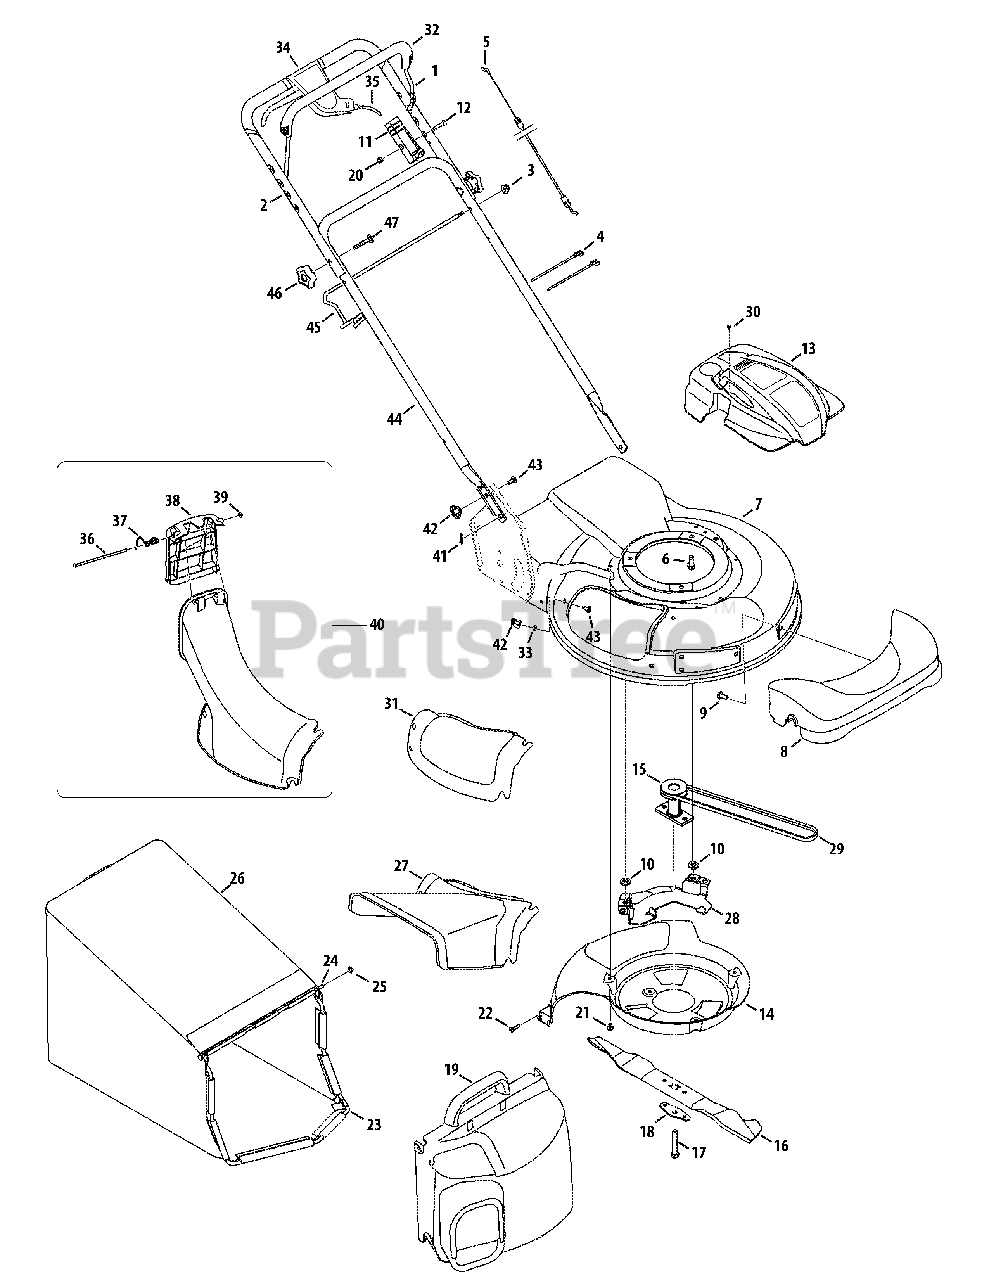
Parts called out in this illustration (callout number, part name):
1	Blade Control
3	Flange Lock Nut, 5/16-18
4	Cable Tie
5	Control Cable
6	TT Screw, 3/8-16 x 1.00
8	Front Axle Cover
9	HL Screw, 5/16-14 x .750
10	Washer, Flat, .407 x .812 x .135
11	Control Cable Mount
12	Screw, 1/4-20 x 1.50
13	Engine Shroud
14	Rear Baffle
15	Blade Adapter
16	21-inch Mulching Blade
17	HH Cap Screw, 3/8-24 x 2.50
18	Bell Blade Spacer
19	Grass Bag Cover Assembly
20	Flange Lock Nut 1/4-20
21	TT Screw 1/4-20 x .375
22	HL Screw 1/4-15 x .75
23	Grass Bag Frame
24	Grass Bag Pivot Rod
25	Cap Speed Nut
26	Grass Bag
27	Side Discharge Chute
28	Belt Keeper
30	Screw, #12-16 x 1.00
31	Mulch Cover
32	Bail Cover
34	Drive Control Assembly
35	Drive Cable
36	Chute Door Pivot Rod
37	Torsion Spring
38	Top Discharge Door Chute
40	Top Discharge Chute Assembly
41	Cotter Pin
42	Wing Nut
43	Carriage Screw 1/4-20 x .75
45	Grass Bag Support Rod
47	Carriage Bolt 5/16-18 x 2
